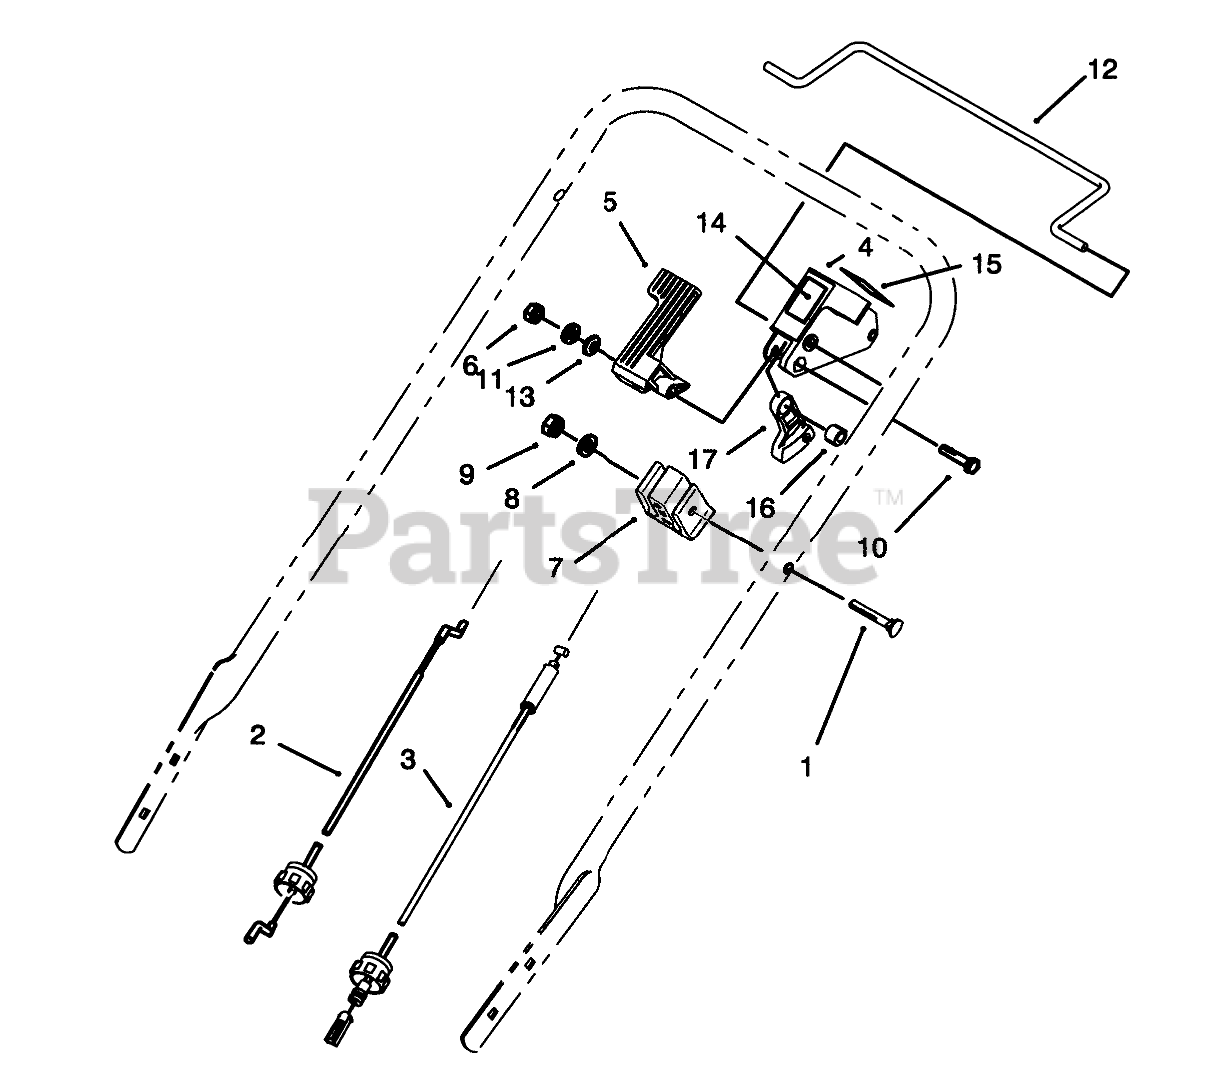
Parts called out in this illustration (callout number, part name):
1	SCREW-HANDLE
2	BRAKE CONTROL
3	CABLE-TRACTION
4	Stop-Pivot
5	LEVER - SHIFT
6	NUT-LOCK, NI
7	SUPPORT-CABLE
8	WASHER-FLAT
9	NUT-LOCK, NI
10	SHOULDER BOLT
11	WASHER-PLAIN
12	Bar-Control
13	WASHER - SPRING
14	DECAL - INSTRUCTION
15	DECAL - INSTRUCTION
16	SPACER-LEVER, TRACTION
17	LEVER-TRACTION
